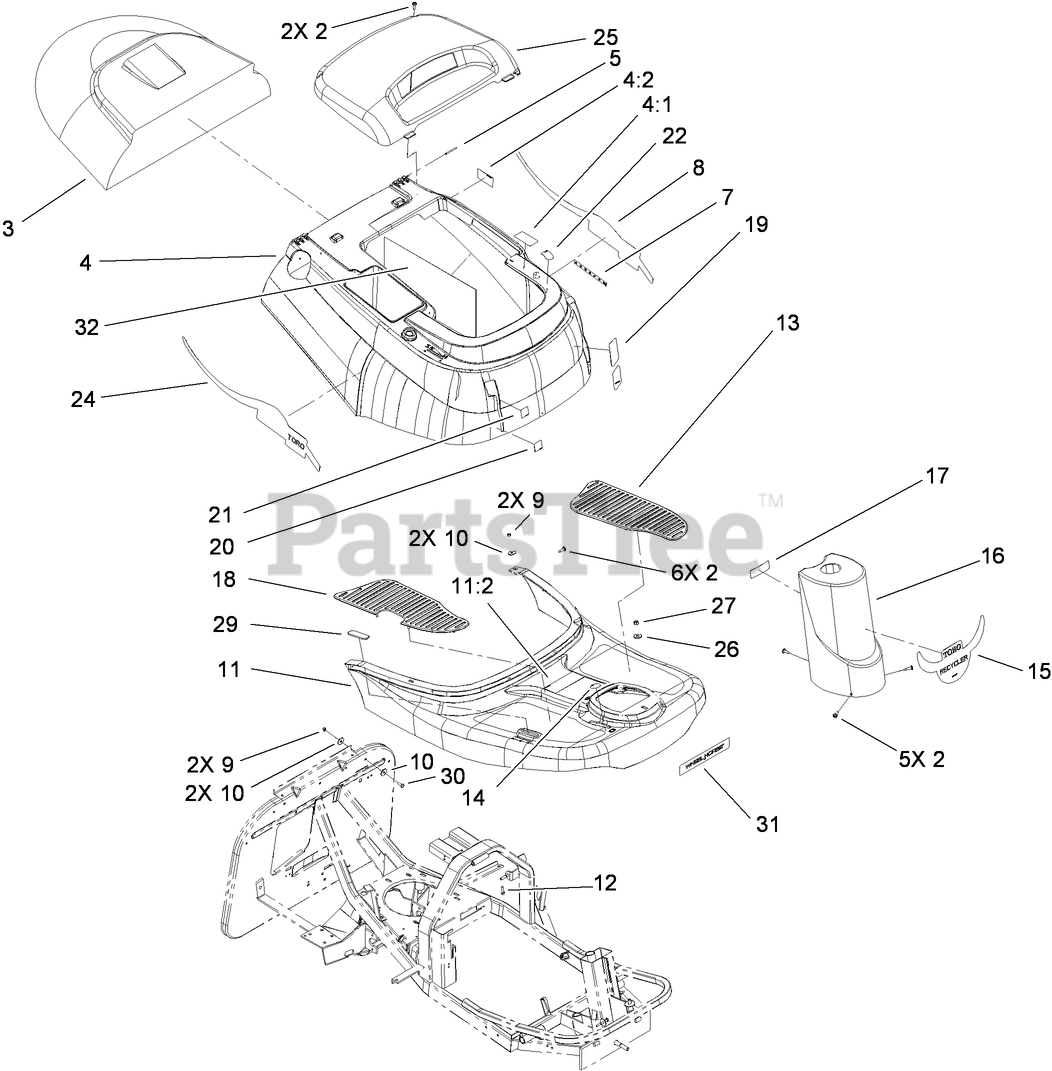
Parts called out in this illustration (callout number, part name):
2	Screw-HH, TAP
3	COVER-GRASS BAG
4	Shroud And Decal ASM
4:1	Decal-Danger
4:2	Loose Parts Package
5	Pin-Dowel
7	Loose Parts Package
9	NUT-LOCK
10	Washer-Flat
11	FOOT REST AND DECAL ASM
11:2	Loose Parts Package
12	SCREW-HH
13	Floormat-LH
14	Loose Parts Package
15	DECAL-FRONT
16	Steering-Turret
17	Loose Parts Package
18	Floormat-RH
19	Loose Parts Package
20	Loose Parts Package
21	Loose Parts Package
22	Loose Parts Package
25	Cover-Engine
26	Washer-Flat
27	NUT-LOCK
30	SCREW-HH
32	INSULATION
